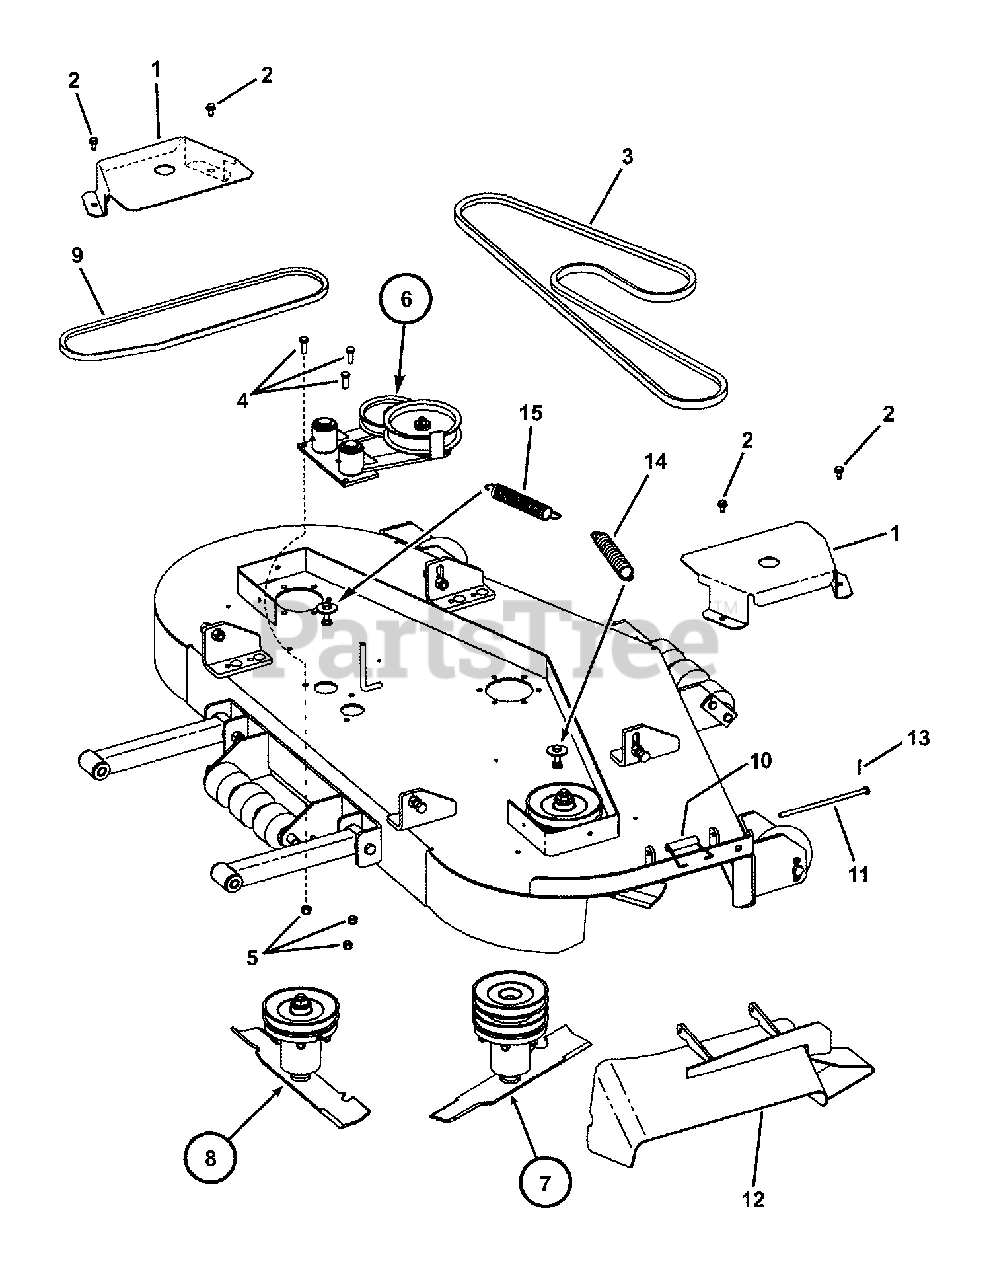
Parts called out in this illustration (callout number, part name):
1	BELT COVER
2	SCREW, 5/16-18 x 5/8" Hex Washer Self-Tap
3	V-BELT, Secondary- 61" (HB Section, 127.0" effective length)
4	BOLT, 3/8-16 X 1" GD5 CZ
5	NUT, 3/8-16 HEX NYLON LOCK
6	ASSEMBLY, Idler
7	ASSEMBLY, Center Spindle
8	ASSEMBLY, Spindle
9	V-BELT, HB Sect. (nom. effective length 94.2")
10	SPRING, Chute
11	PIN, Chute Hinge
12	WELDMENT, Chute Deflector (61" Euro)
13	PIN, 3/32 x 1" Cotter
14	SPRING, Idler Primary (1.25" O.D. x 10" long)
15	SPRING, Idler (1.17" O.D. x 7.5" long)
